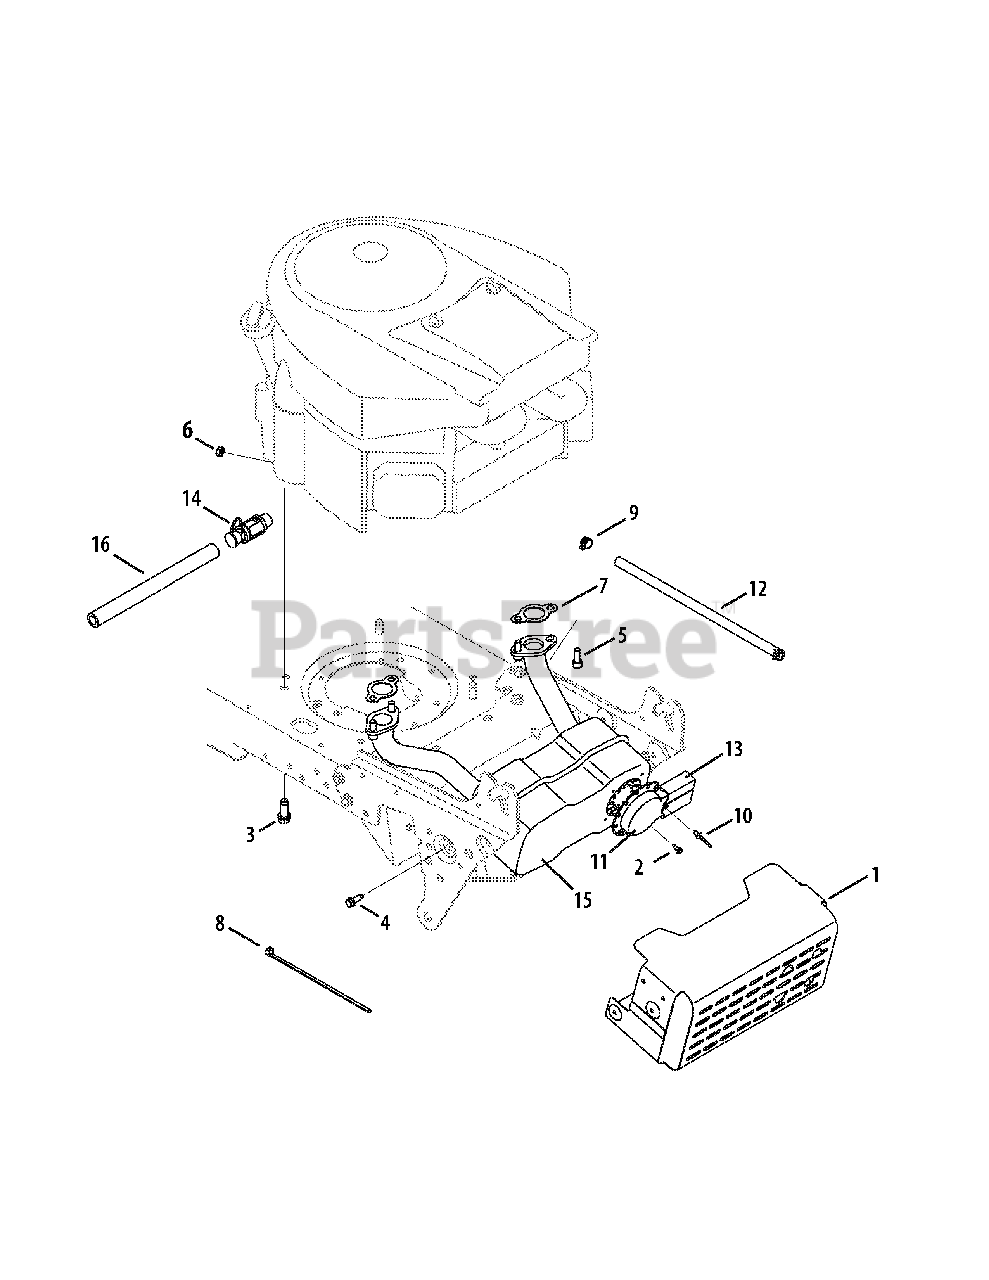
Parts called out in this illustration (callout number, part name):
1	Muffler Shield Assembly
2	Screw, #8-18, 0.500
3	Screw, Hex, 3/8-16 x 1.00
4	Screw, Hex, 1/4-20, 0.750
5	Screw, 5/16-18, 0.75
6	Sems Nut, 1/4-20
7	Exhaust Gasket, B&S Twin
8	Cable, Tie, 3/16 x .05 x 7.4
9	Hose Clamp
10	Rivet, Pop, .188 x .325
11	Deflector, Muffler
12	Fuel Line, Low Permeation
13	Extension, Deflector
14	Drain, Oil
15	Muffler, Dual Inlet, B&S
16	Extension Hose, Oil Drain
